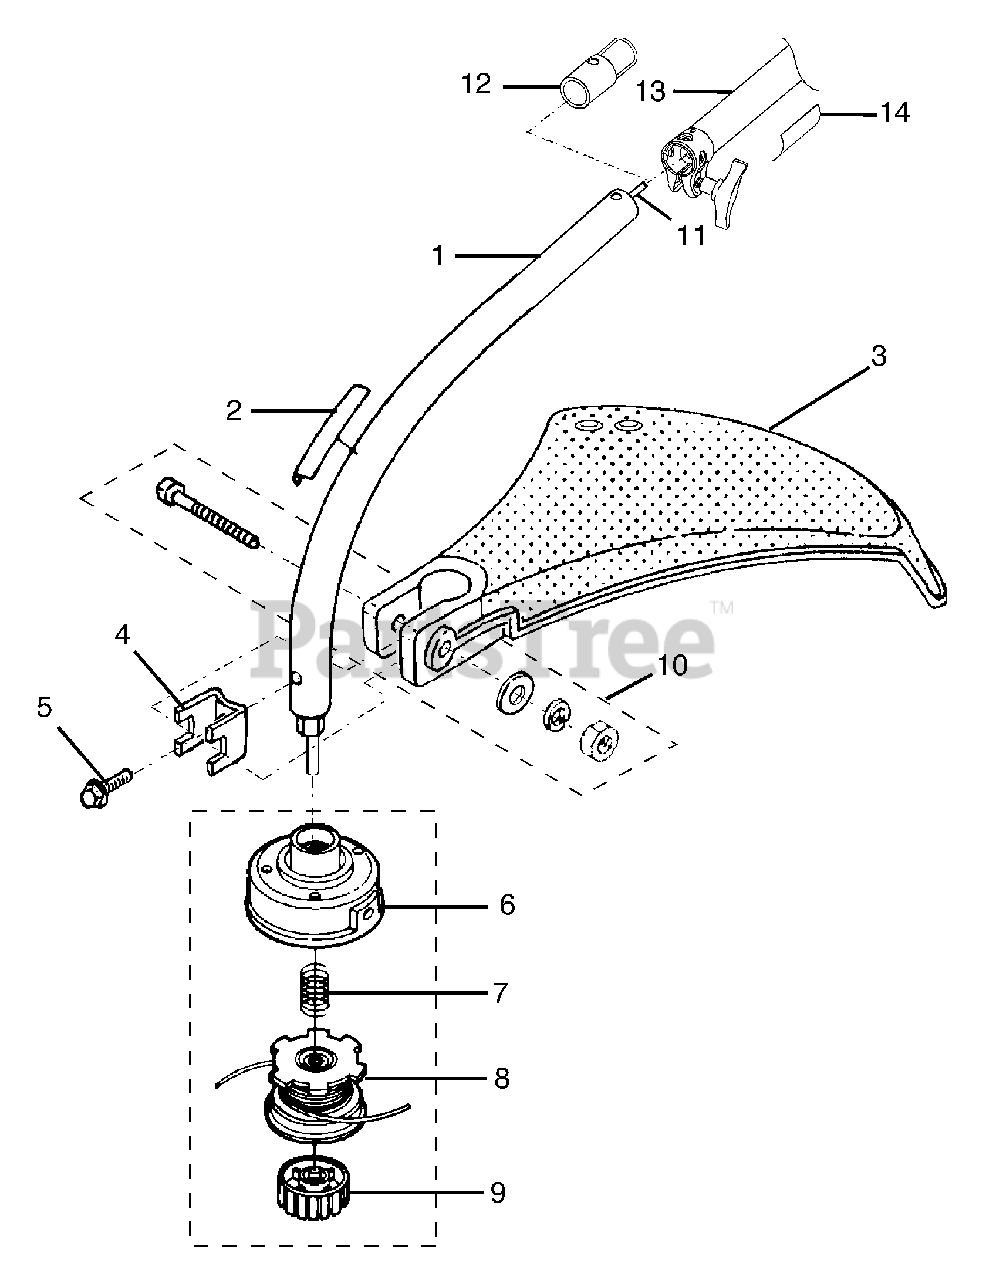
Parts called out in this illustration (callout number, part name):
1	LOWER DRV. SHAFT HOUSING & DECAL
2	BOOM DECAL (WARNING)
3	GRASS DEFLECTOR
4	CLAMP
5	SCREW
6	HOUSING AND EYELETS
7	COMPRESSION SPRING
8	SPOOL W/LINE (.80 in.)
9	SPOOL RETAINER (RH/THREAD)
10	FASTENER PARTS KIT
11	FLEX SHAFT
12	END CAP STORAGE
13	UPPER DRV. SHAFT ASSY. & DECAL
14	LABEL, UPPER BOOM WARNING
